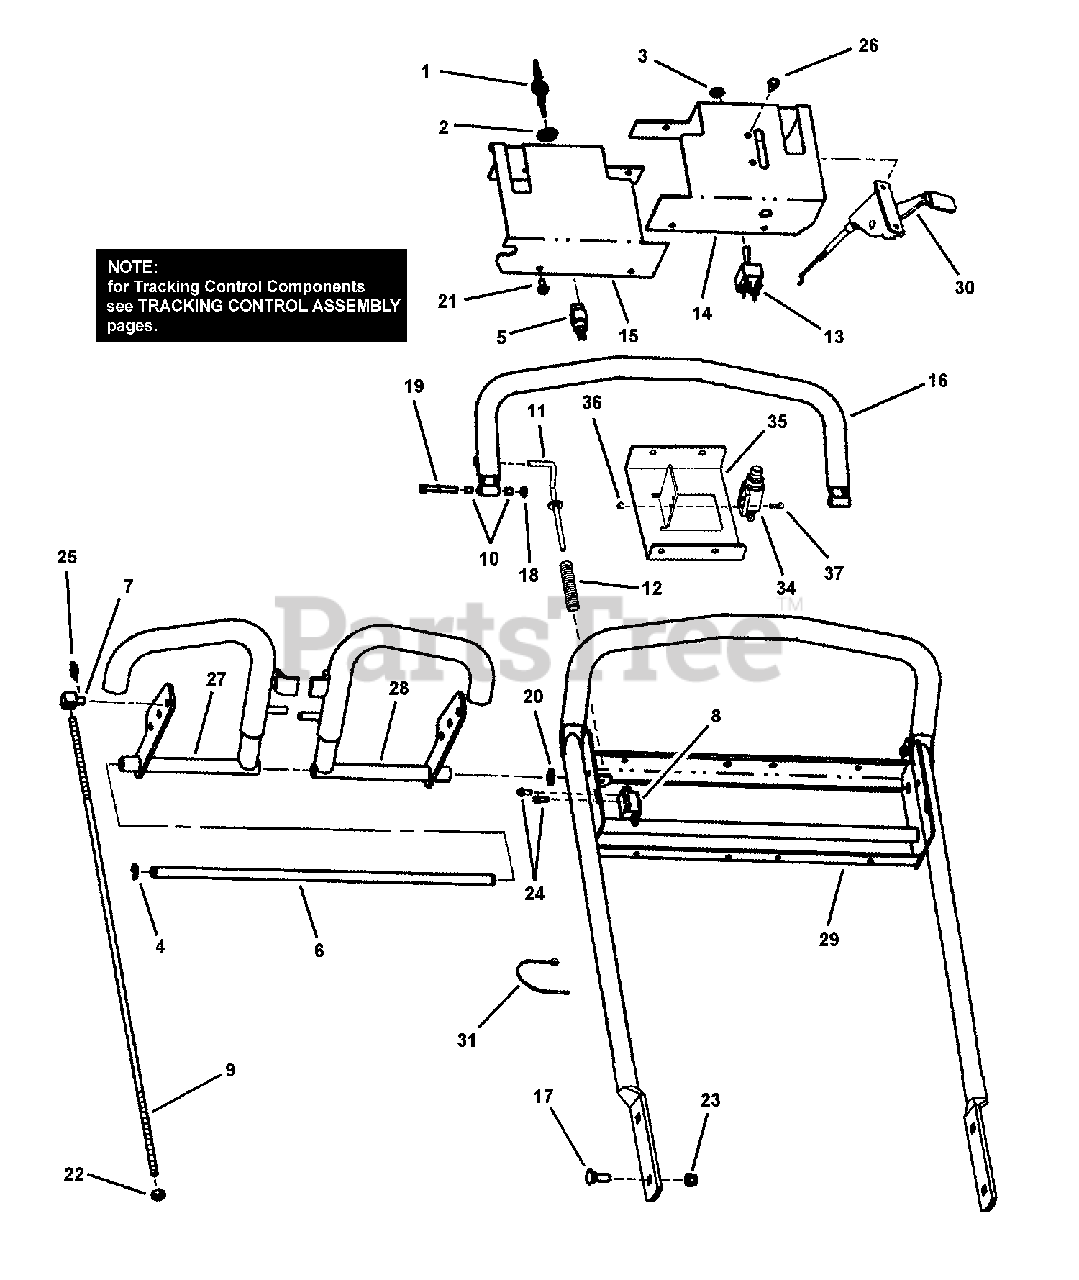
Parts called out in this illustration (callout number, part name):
1	IGNITION KEY, Pair
2	NUT, 5/8-32 Hex (Ignition Switch)
3	NUT, 1/2-27 Hex (Special)
4	RETAINING RING
5	SWITCH, Ignition, 2-Pole, Recoil Start
6	ROD, Pivot, 1/2" Dia. x 18.542 w/2 retaining Ring Grooves
7	SWIVEL
8	SWITCH, OPC, Single Pole (NC)
9	CONTROL ROD, Traction (5/16-24 threads)
10	BEARING, Nyliner
11	ROD, Operator Presence Control
12	SPRING, OPC- Loop Handle
13	SWITCH, Toggle
14	PANEL, Left
15	PANEL, Right
16	BAIL, Operator Presence Control (Weldment)
17	BOLT, 5/16-18 x 1" Short Neck Carriage, GR 5
18	NUT, 1/4-20 Hex Jam
19	BOLT, 1/4-20 x 1-3/4" Hex Head Cap, GR 5
20	BUSHING, 1/2" Machine
21	SCREW, 1/4-20 x 1/2" Hex Washer Self-Tap
22	NUT, 5/16-24 Hex, GR 5
23	NUT, 3/8-16 HEX NYLON LOCK
24	SCREW, #12-14 x 1/2" Hex Flange Self-Tap
25	COTTER PIN, 1/2" Self-Locking
26	SCREW, 1/4-20 x 3/4" Hex Washer Self-Tap
27	WELDMENT, Traction Lever, RH
28	WELDMENT, Traction Lever, LH
29	HANDLE, Loop (Weldment)
30	THROTTLE CONTROL, 51.50/0.90
31	CABLE TIE, 7"
34	SWITCH, Interlock, Sealed (NC)
35	BRACKET, Interlock Switch
36	NUT, #10-32 Hex Nyloc
37	SCREW, #10-32 x 5/8" Hex Machine
